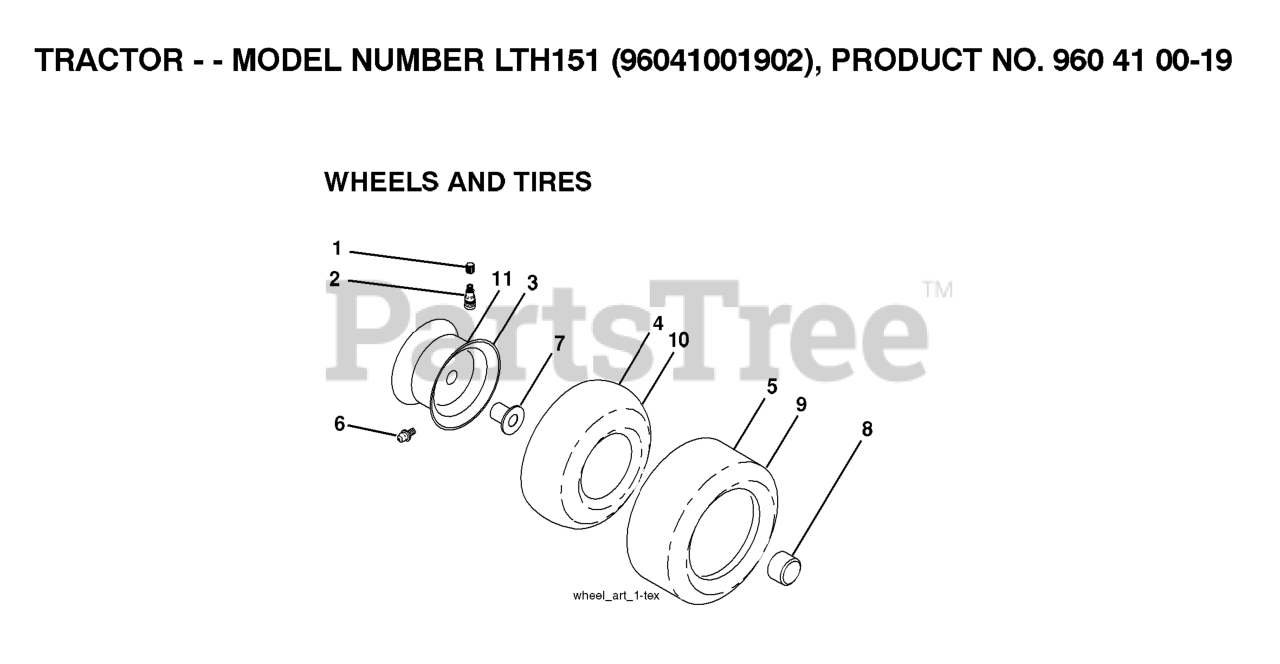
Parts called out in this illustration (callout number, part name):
2	VALVE STEM LT
3	RIM ASM 6" FRONT SILVER
4	TUBE.5.3/4.5/6
5	TIRE HEAVY DUTY
6	FITTING LT
7	BEARING T
8	CAP, AXLE BLK
9	TIRE HEAVY DUTY
10	TUBE
11	RIM ASM 8" REAR SILVER
